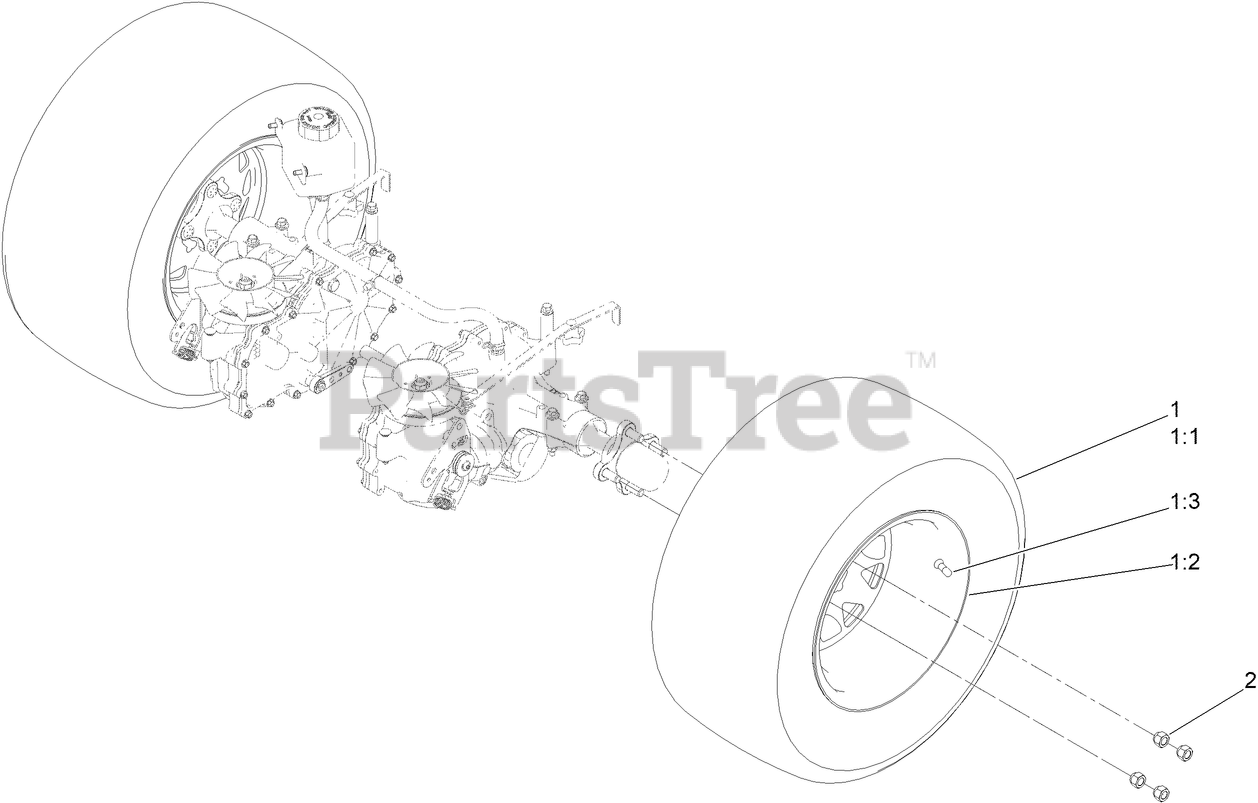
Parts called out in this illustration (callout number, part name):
1	WHEEL AND TIRE ASM
1:1	TIRE-VOODOO
2	NUT-LUG
